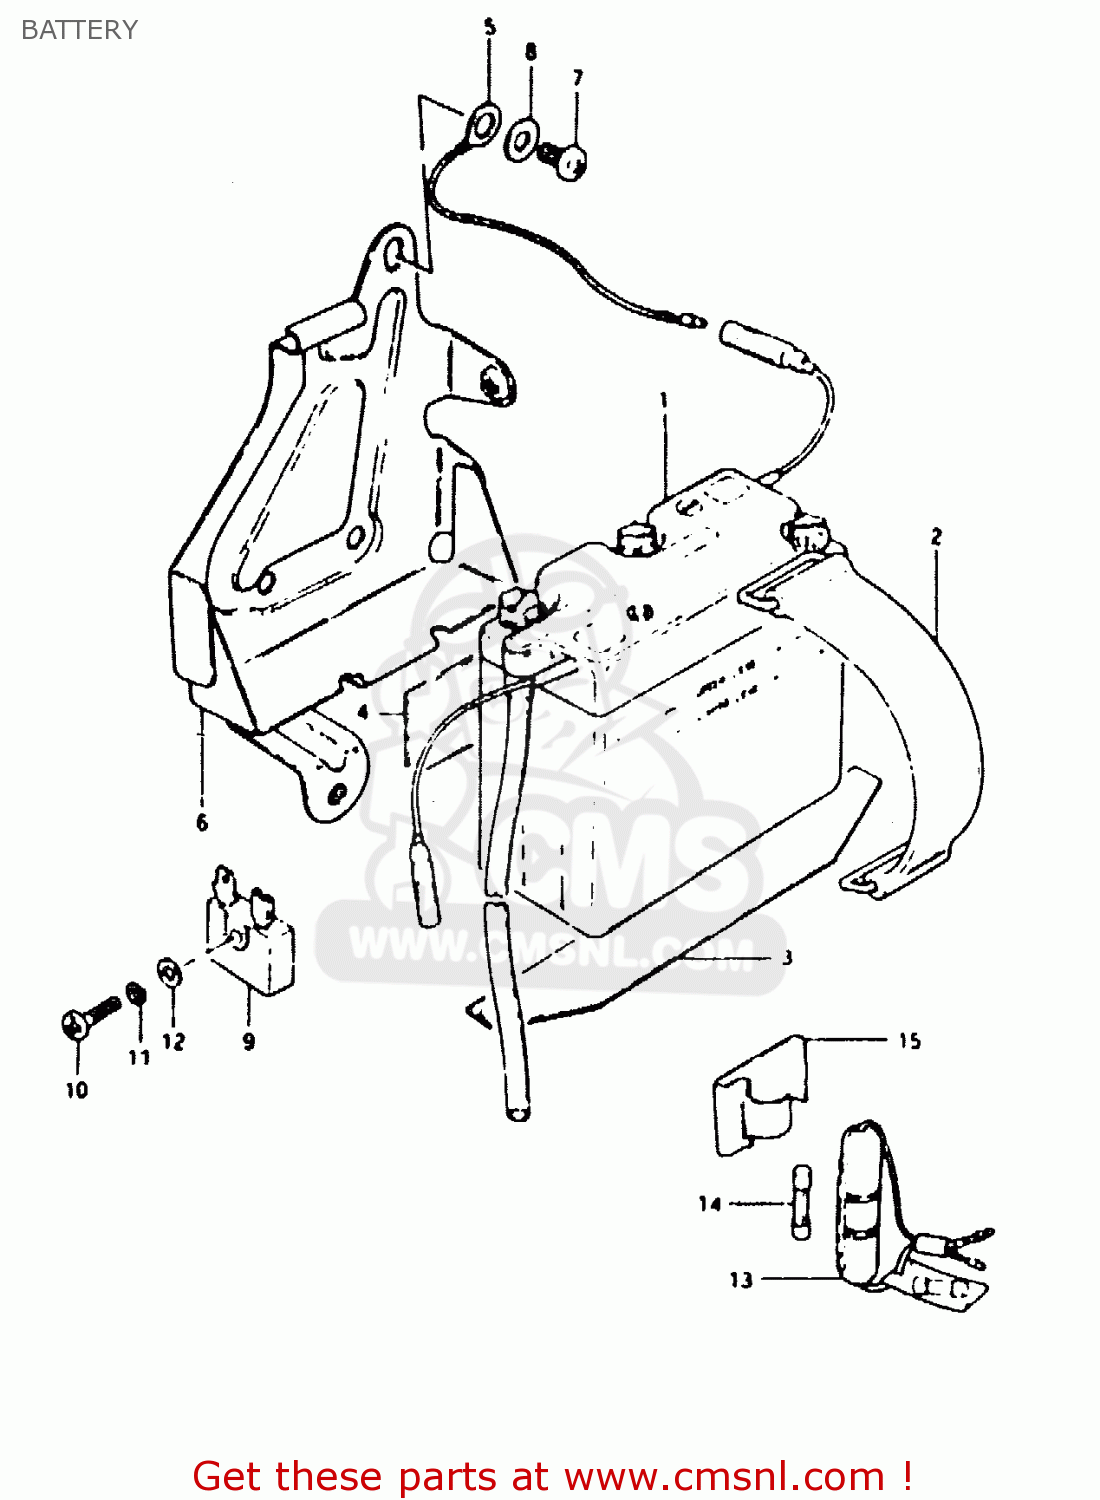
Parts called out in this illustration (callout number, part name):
1	BATTERY(6N4B-2A,6V4.2AH)
2	BAND
3	PROTECTOR,BATTERY
4	PROTECTOR(170X95X3.0)
5	LEAD WIRE
6	HOLDER, BATTERY
7	SCREW 6X12
8	WASHER
9	RECTIFIER ASSEMBLY
10	SCREW 5X20
11	LOCK WASHER
12	WASHER
13	BOX ASSEMBLY,FUSE
14	FUSE(10A)
15	HOLDER,FUSE CASE
